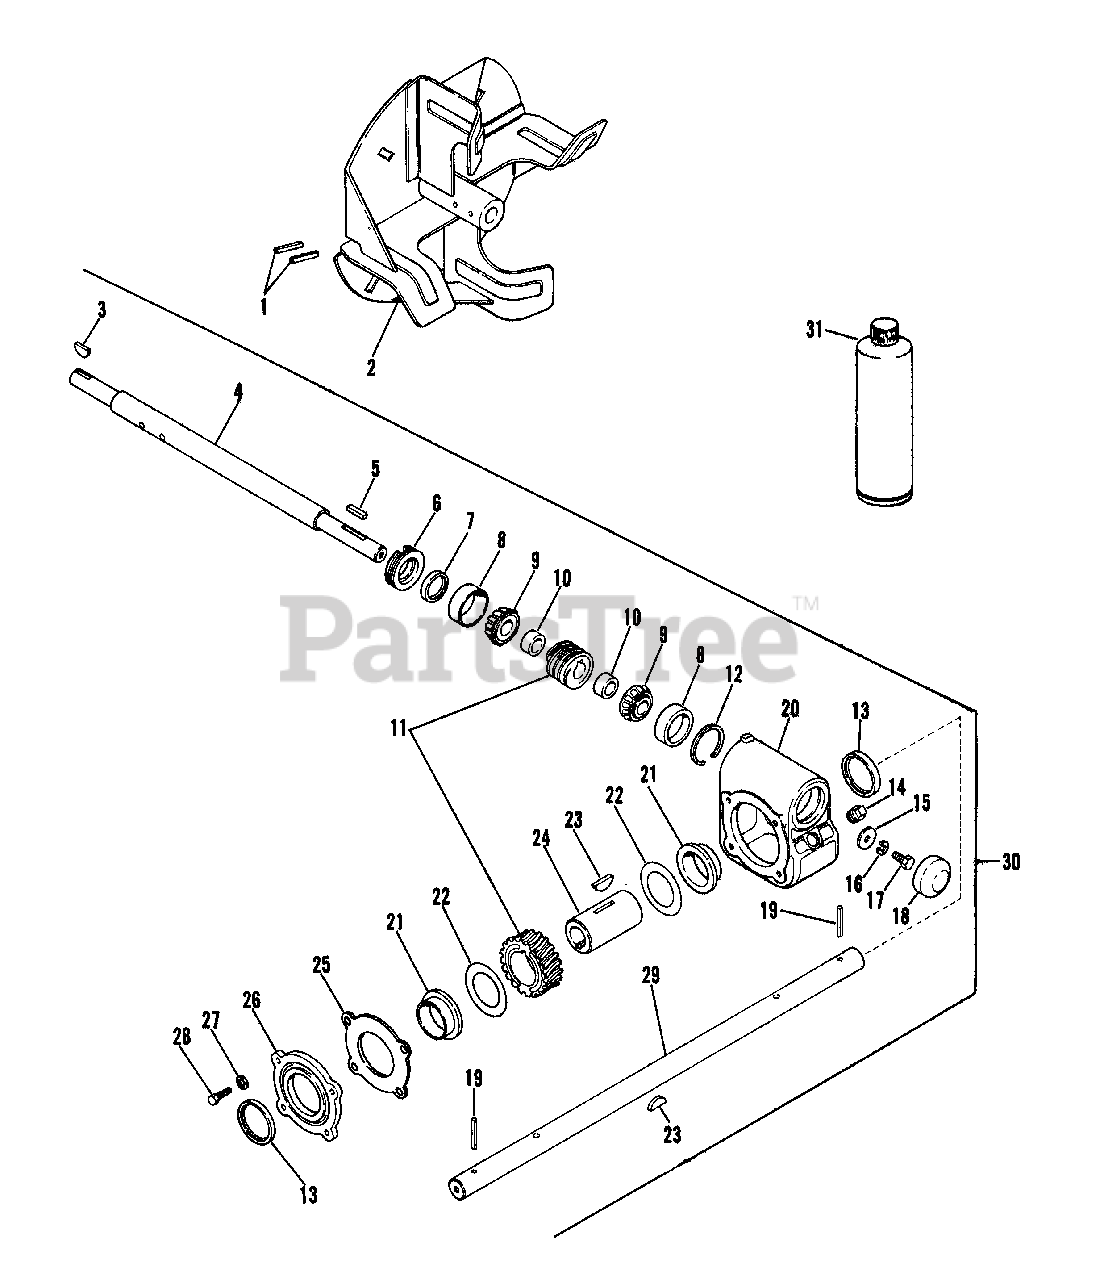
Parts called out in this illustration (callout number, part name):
1	PIN-ROLL .313X1.75
2	FAN - 14"
3	KEY-WDRF .188X.875X.375 SAE11
4	SHAFT, WORM - 1.00 DIA.
5	KEY-SQ .188X1.0X.188 SAE 8630
6	ADJUSTMENT PLUG - 1" SHAFT
7	SEAL 1.000X1.312X.150
8	BRG-CUP 1.781X.475
9	BRG-CONE .750X.61
10	BOLT, HEX HEAD
11	WORM & GEAR SERVICE ASSEMBLY
12	RG-RTNG-INT 1.781X.062
13	SEAL 1.625X2.125X.250
14	PIPE PLUG
15	WSHR-FL-STL .328X1.0X.094
16	WSHR-LK .313X.093 MED HICLR
17	BLT-HEX .31-18X.75 PL GR2
18	DUST CAP
19	PIN-ROLL .188X1.50
20	GEAR CASE - CAST IRON
21	BSHG-FLG .683X1.87X1.68X2.250
22	WSHR-FL-STL 1.625X2.500X.012
23	KEY-WDRF .25X.875X.375 SAE A
24	GEAR CASE SHAFT
26	GEAR CASE COVER
27	WSHR-LK-EXT. 250 ID
28	BLT-HEX .25-20X.75 PL GR2
29	SHAFT, 32" RAKE - 1.00 DIA.
29	SHAFT, 28" RAKE - 1.00 DIA.
29	SHAFT, 36" RAKE - 1.00 DIA.
30	GEAR CASE - CAST IRON
31	ARIENS 16 OZ.BOTTLE OF L2 LUBE
